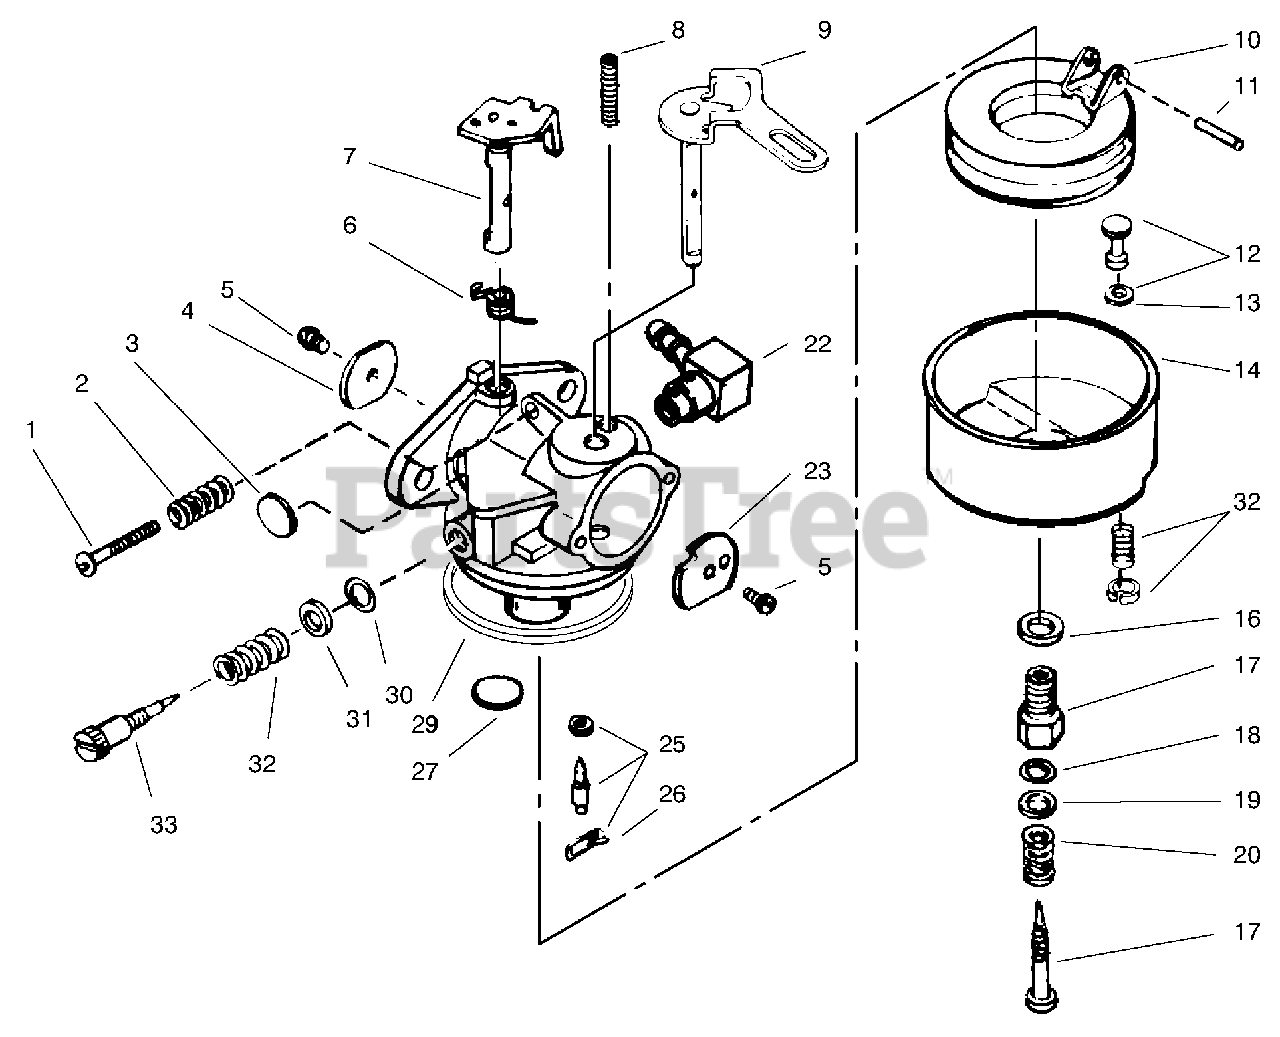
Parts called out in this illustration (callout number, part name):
1	Screw Idle
3	Plug-Welch
4	Shutter Throttle
6	Spring-Return
7	Shaft & Lever
8	Spring-Choke
9	Shaft & Lever Asm.
11	Float Shaft
12	Drain Assembly-Bowl (Incl. Ref. #13)
13	Gasket-Bow Drain
14	Bowl-Assembly (Incl. Ref. #12 & 13)
16	Gasket
17	Screw Adjustment Assembly (Incl. Ref. #16-20)
18	"O"Ring
22	Fitting-Fuel
23	Choke Shutter
25	Inlet Needle-Seat & Clip (Incl. Ref. #26)
27	Plug
29	Gasket
30	"O"Ring
33	Screw-Idle
